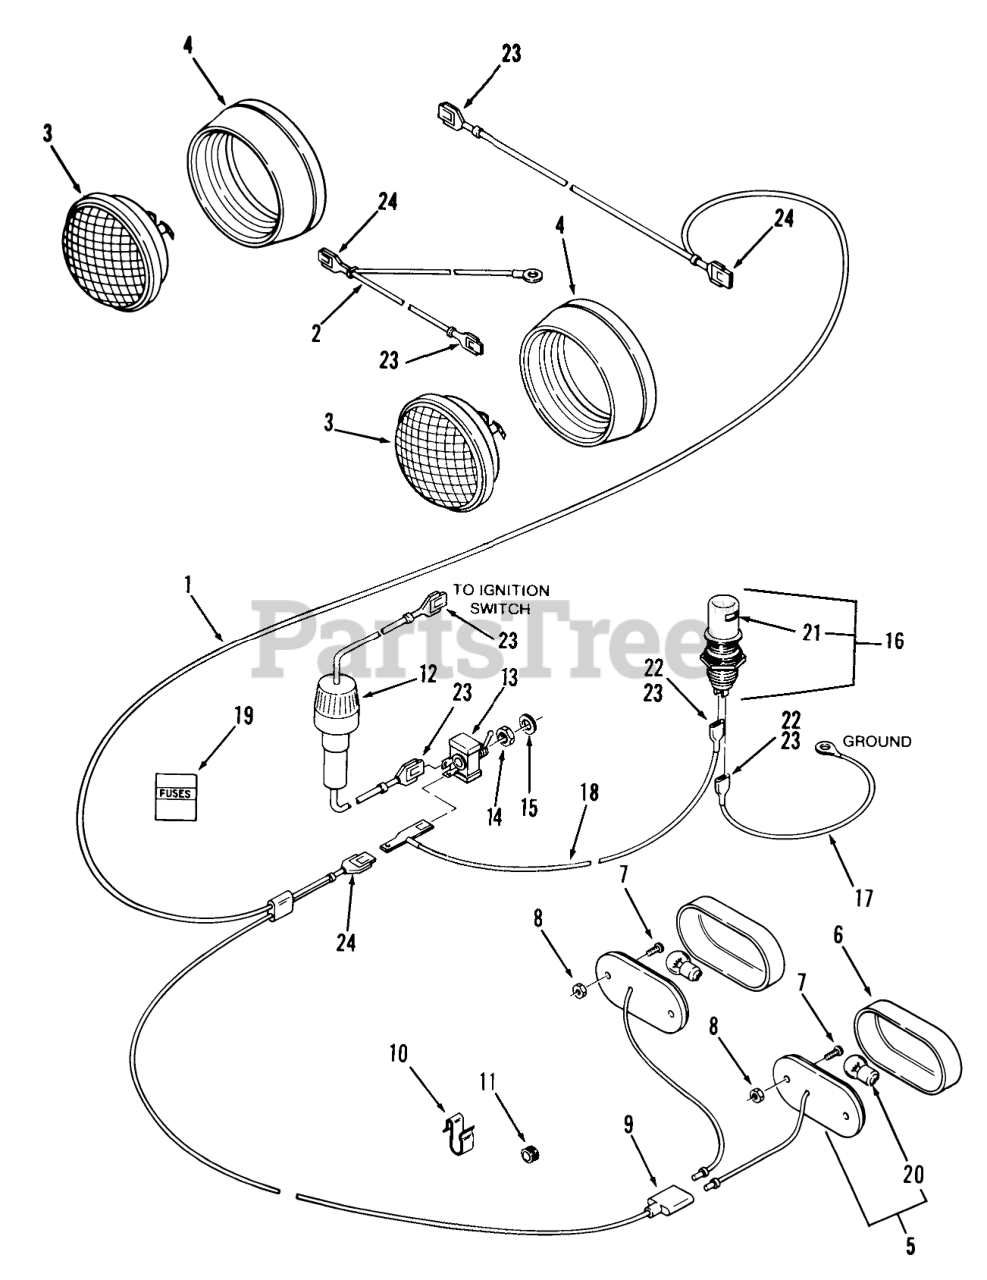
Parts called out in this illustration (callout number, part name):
1	Control Clip
2	Wire Assy
3	HEADLAMP
4	Grommet
5	BASE-TAIL LIGHT
6	Lens-Taillight
7	Screw
8	HEX NUT 10-32 E.S.
9	CONNECTOR 3 WIRE
10	SPEED CLIP
11	Grommet
12	ASSY FUSED CONNECTOR
13	SWITCH-LIGHTS
14	Nut, Knurled
15	NUT-HEX
16	LAMP-DASH
17	SY WIRE HR METER G
18	Wire Assy
20	Bulb
21	Bulb (#1815)
22	CONNECTOR BODY ELECT
23	Terminal
24	TERMINAL-TAB RCPT
